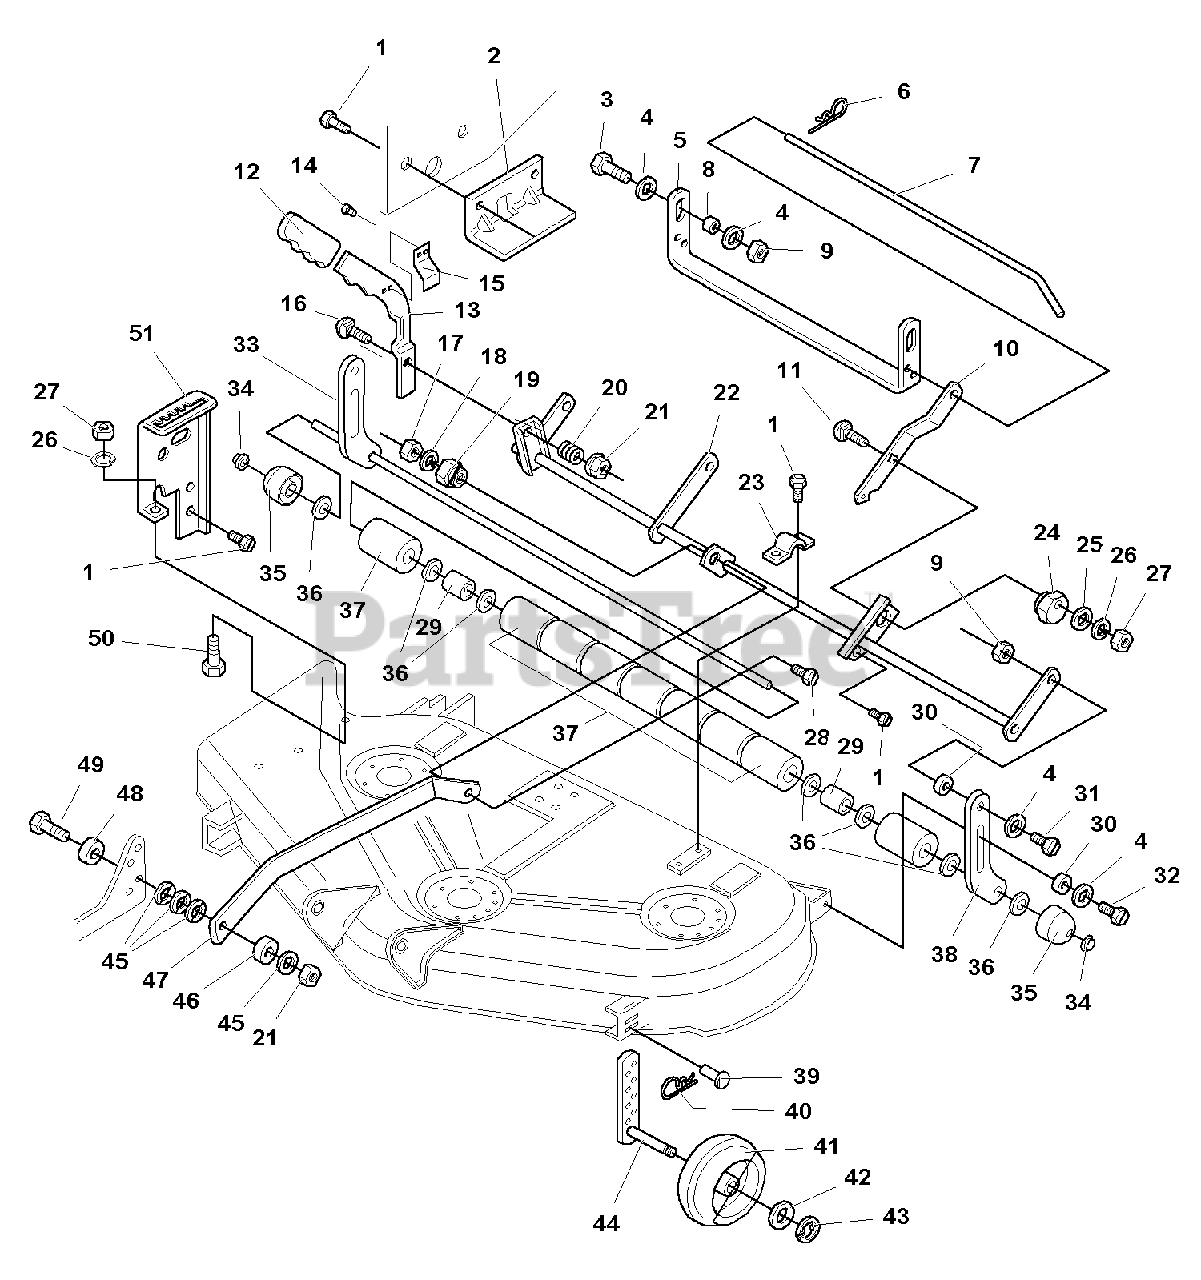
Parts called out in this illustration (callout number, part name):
1	CAPSCREW, Taptite Hex Washer Head, 5/16-18 x 3/4
2	BRACKET, Upstop
3	CAPSCREW, Hex Head, 5/16-18 x 1-1/4
4	WASHER, 5/16
5	BRACKET, U
6	CLIP, Spring
7	ROD, Transport
9	NUT, Hex Lock, 5/16-18
11	CARRIAGE BOLT, 5/16-18 x 1-1/4
13	ARM, Adjustment
15	SPRING, Handle
16	CARRIAGE BOLT, 3/8-16 x 1-3/4
17	NUT, Hex, 3/8
18	WASHER, Lock, 3/8
19	NUT, Hex Adjusting, .99 DIA .687
21	NUT, Hex Flange Lock, 3/8-16
22	ARM ASSEMBLY, Rocker
23	STRAP
25	WASHER, 5/16
26	LOCKWASHER, 5/16
27	NUT, Hex, Full, 5/16-18
28	CARRIAGE BOLT, 3/8-16 x 1-1/2
29	SPACER, 1-1/4 x 5/8
31	CAPSCREW, Hex Head, 5/16-18 x 1
32	CAPSCREW, Taptite Hex Washer Head, 5/16-18 x 1
33	SHAFT ASSEMBLY, 44"
34	PUSHNUT, 5/8
35	ROLLER, End
36	WASHER, 5/8
38	BAR, Roller, Support
40	CLIP, Hairpin
41	WHEEL, Gauge
42	WASHER, 1/2
43	E-RING, 1/2
44	ARM ASSEMBLY, Adjustable
45	WASHER, 3/8
47	ARM, Pitch
49	CAPSCREW, Hex Head, 3/8-16 x 2
50	CAPSCREW, Hex Head, 5/16-18 x 3/4
